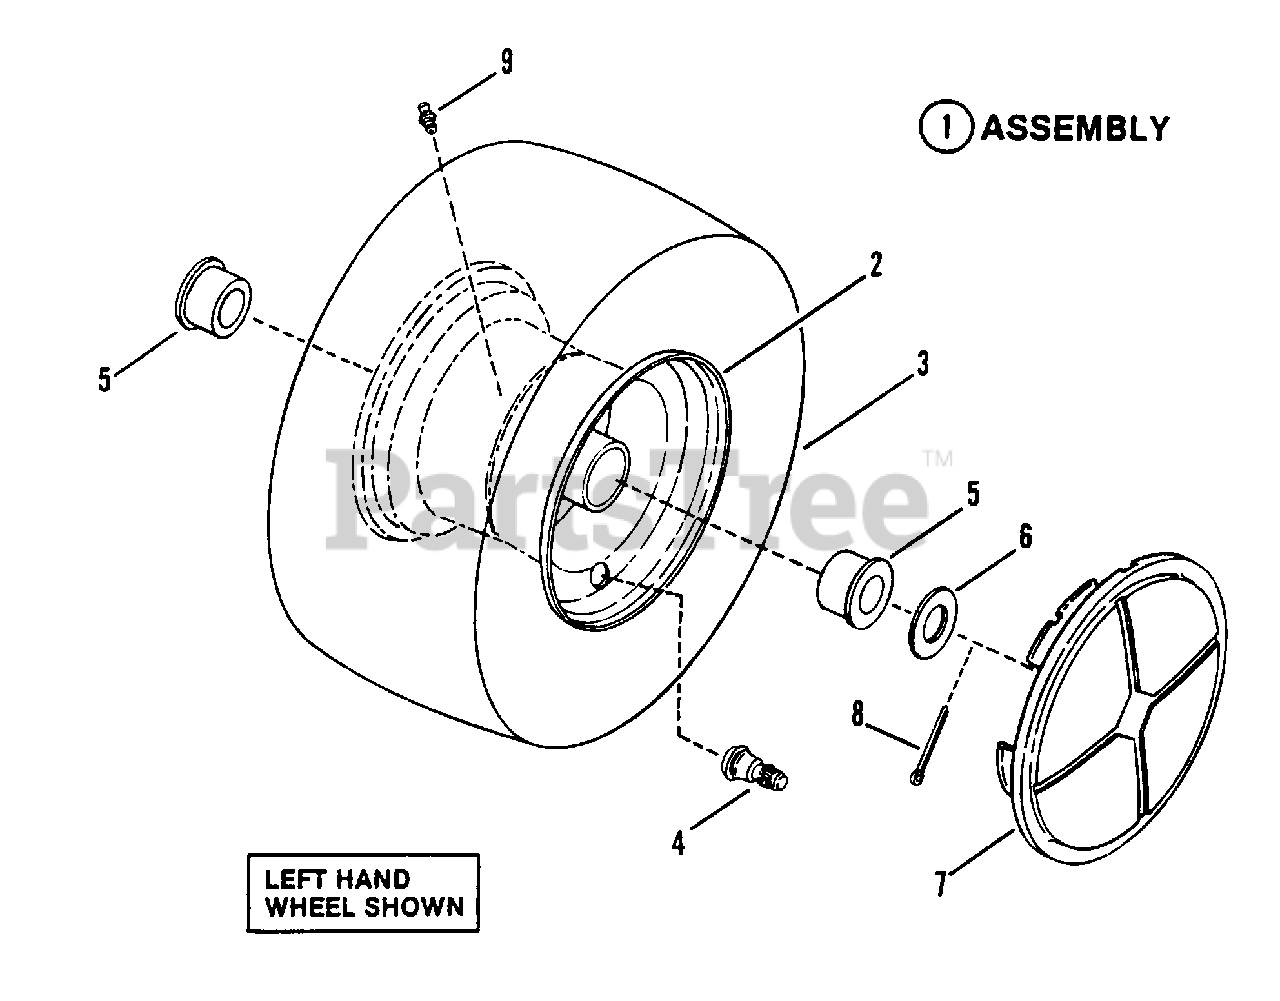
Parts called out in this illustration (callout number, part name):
1	ASSEMBLY, Front Tire & Rim
2	RIM, 6 x 4.50
3	TIRE, 15-6.00 x 6
4	VALVE, Air (Snap-in)
5	BEARING, Wheel
6	WASHER
7	WHEEL-COVER
8	COTTER-PIN
9	FITTING, Lube 1/4-28 Tapered Thread
